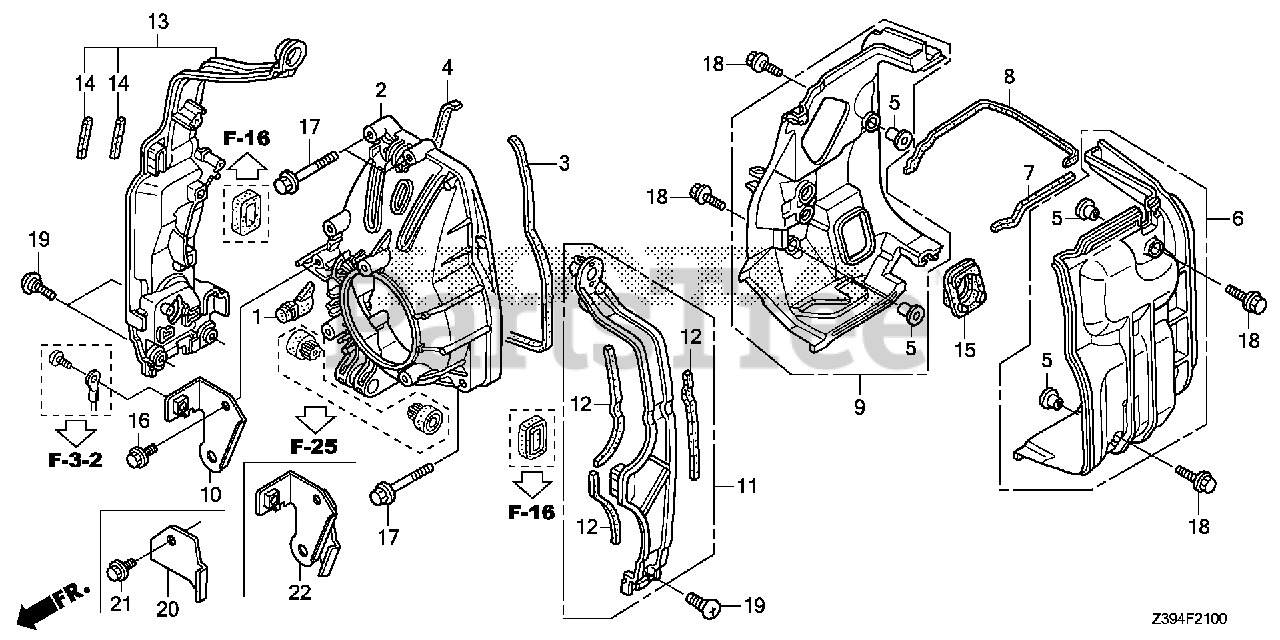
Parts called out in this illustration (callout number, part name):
1	RUBBER, TANK PROTECTOR
2	COVER, FAN
3	SEAL, R. FAN COVER (L. SIDE)
4	SEAL, L. FAN COVER (R. SIDE)
5	COLLAR, FAN COVER
6	SHROUD, R. (L. SIDE)
7	SEAL, R. SHROUD (UPPER) (L. SIDE)
8	SEAL, L. SHROUD (UPPER) (R. SIDE)
9	SHROUD, L. (R. SIDE)
11	FRAME ASSY., R. FR. (L. SIDE)
12	SEAL, R. FR. FRAME (L. SIDE)
13	FRAME ASSY., L. FR. (R. SIDE)
14	SEAL, L. FR. FRAME (R. SIDE)
15	RUBBER, OIL CHECK
17	BOLT, FLANGE (6X45) (CT200)
18	BOLT, FLANGE (6X23) (CT200)
19	SCREW, SPECIAL (6X15)
20	PLATE, FAN COVER
21	BOLT, FLANGE (6X12) (CT200)
